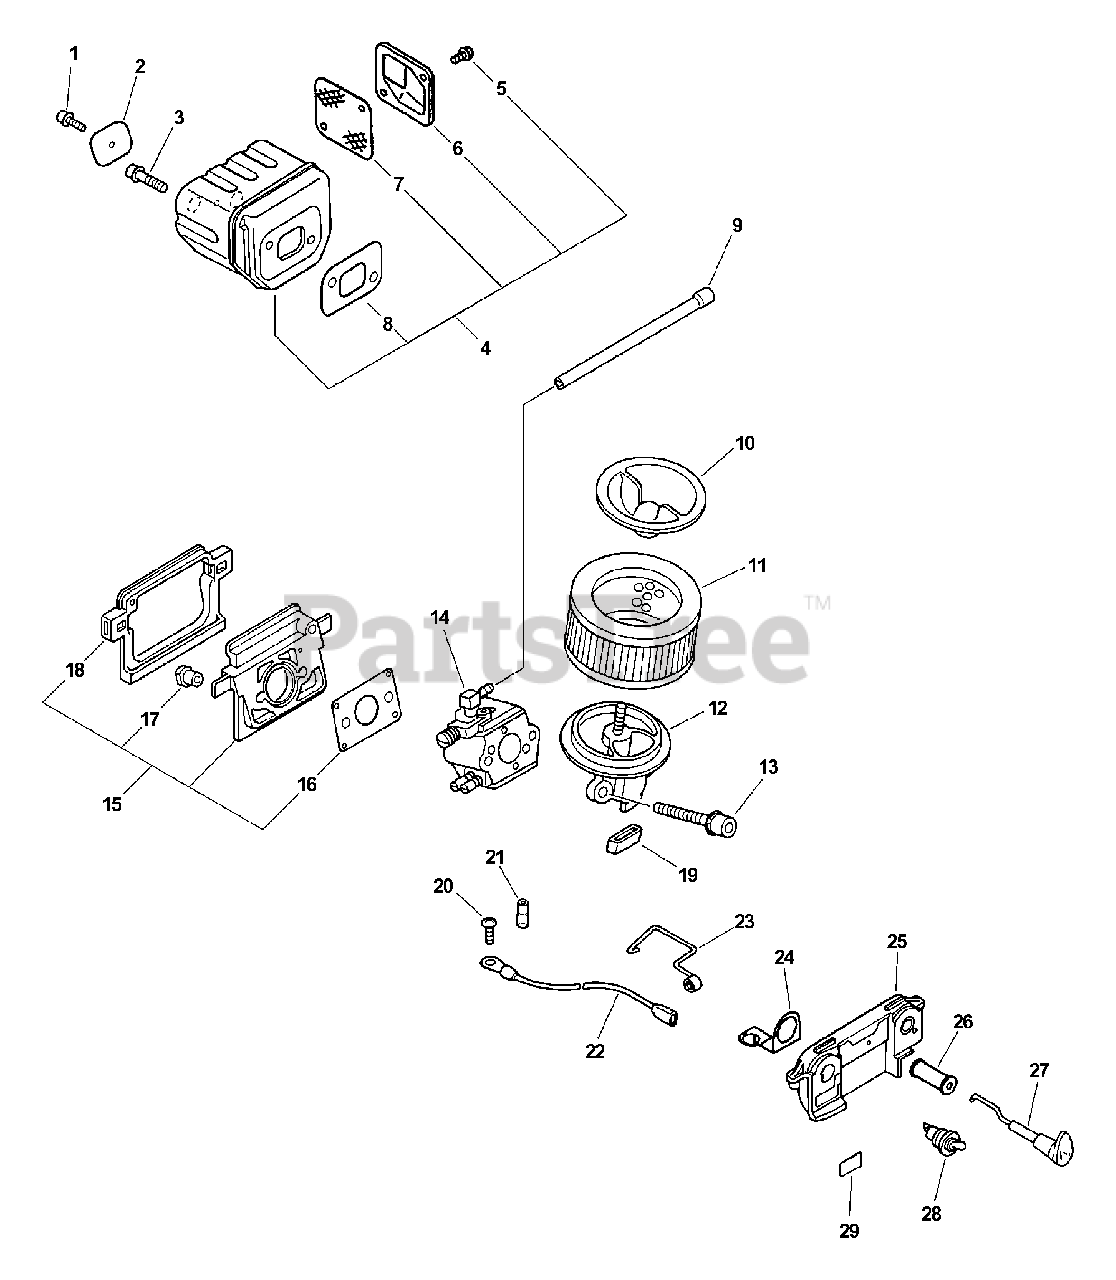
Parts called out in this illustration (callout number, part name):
1	SCREW - 4X6
3	SCREW - 5X14
4	MUFFLER ASSY
5	SCREW - 4X8
6	GUIDE, EXHAUST
7	SCREEN, SPARK ARRESTOR
8	GASKET, EXHAUST
9	PIPE - IMPULSE
10	COVER, AIR FILTER
11	FILTER, AIR
12	MOUNT, AIR FILTER
13	SCREW - 5X50
14	CARBURETOR WT-416C
15	INSULATOR KIT
16	GASKET, INTAKE
18	CUSHION
20	SCREW - 4X6
21	BOOT, CONNECTOR
22	LEAD - GROUND
23	ROD, THROTTLE
24	TERMINAL - GROUND
25	BRACKET, SWITCH
26	GROMMET
27	ROD, CHOKE
28	IGNITION SWITCH ASSY
29	LABEL - STOP
